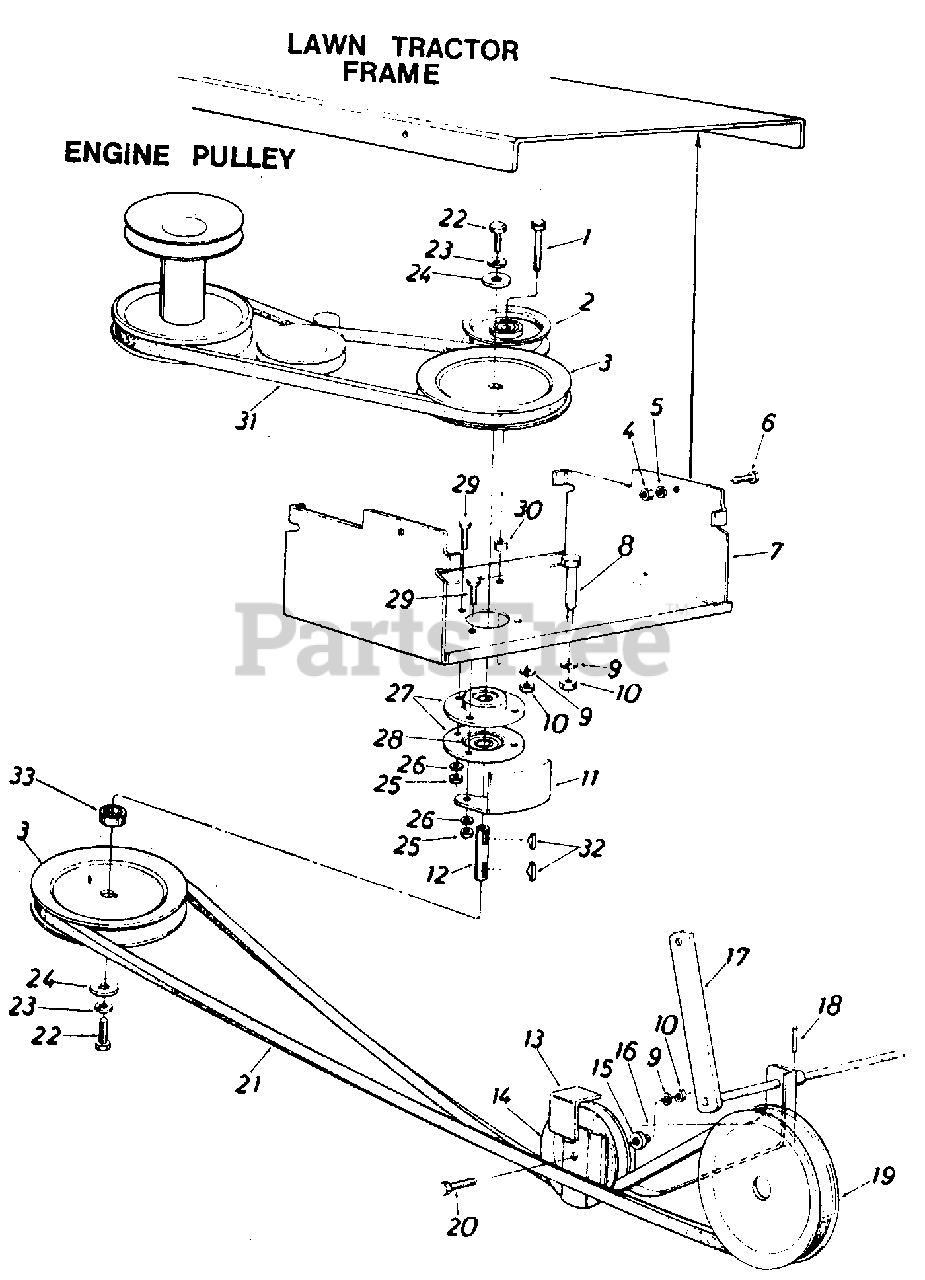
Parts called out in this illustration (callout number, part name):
1	Hex Bolt 3/8-16 x 2.00" Lg
2	Fl.-Idler w/Flanges 3-3/4" O.D.
3	5/8" "V"-Pulley .790" I.D. x .650" O.D.
4	Hex Nut 3/8-24 Thd.
5	L.-Wash. 3/8" I.D. Heavy Duty
6	Hex Bolt 3/8-24 x .88" Lg.
7	Carriage Bracket
8	Shoulder Bolt .498" Dia. x 1.64
9	L.-Wash. 3/8" I.D.
10	Hex Nut 3/8-16 Thd.
13	Belt Separator Plate
14	Fl.-Idler w/Flanges 3.25" 0. D.
15	Fl.-Wash. .406" I.D. x 1.25" O.D. x .164
18	Spring Pin Roll 3/16" Dia. x 1.50" Lg
19	5/8" V-Puliey 1.50" I.D. x 6.50" O.D.
20	Hex Bolt 3/8-16 x 1.75" Lg.*.
21	"V"-Belt 1/2" x 95.0" Lg.
22	Hex Bolt 5/16-18 x .88" Lg. Spec.
23	L. -Wash . 5/16 " I.D.
24	Fl.-Wash. .344" I.D. x 1.125" O.D. x .125
25	Hex Nut 5/16-18 Thd.
26	L.-Wash. 5/16" I.D.
27	Bearing Housing 1.85" I.D.
28	Ball Bearing .787" I.D. x 1.85" O.D.
29	Hex Sems Bolt 5/16-18 x .75"
30	Spacer
31	Belt 1/2" Wide x 52" Long
32	Hi-Pro Key 3/16" x 5/8"
33	Spacer-.80" I.D. x 1.0" O.D.
